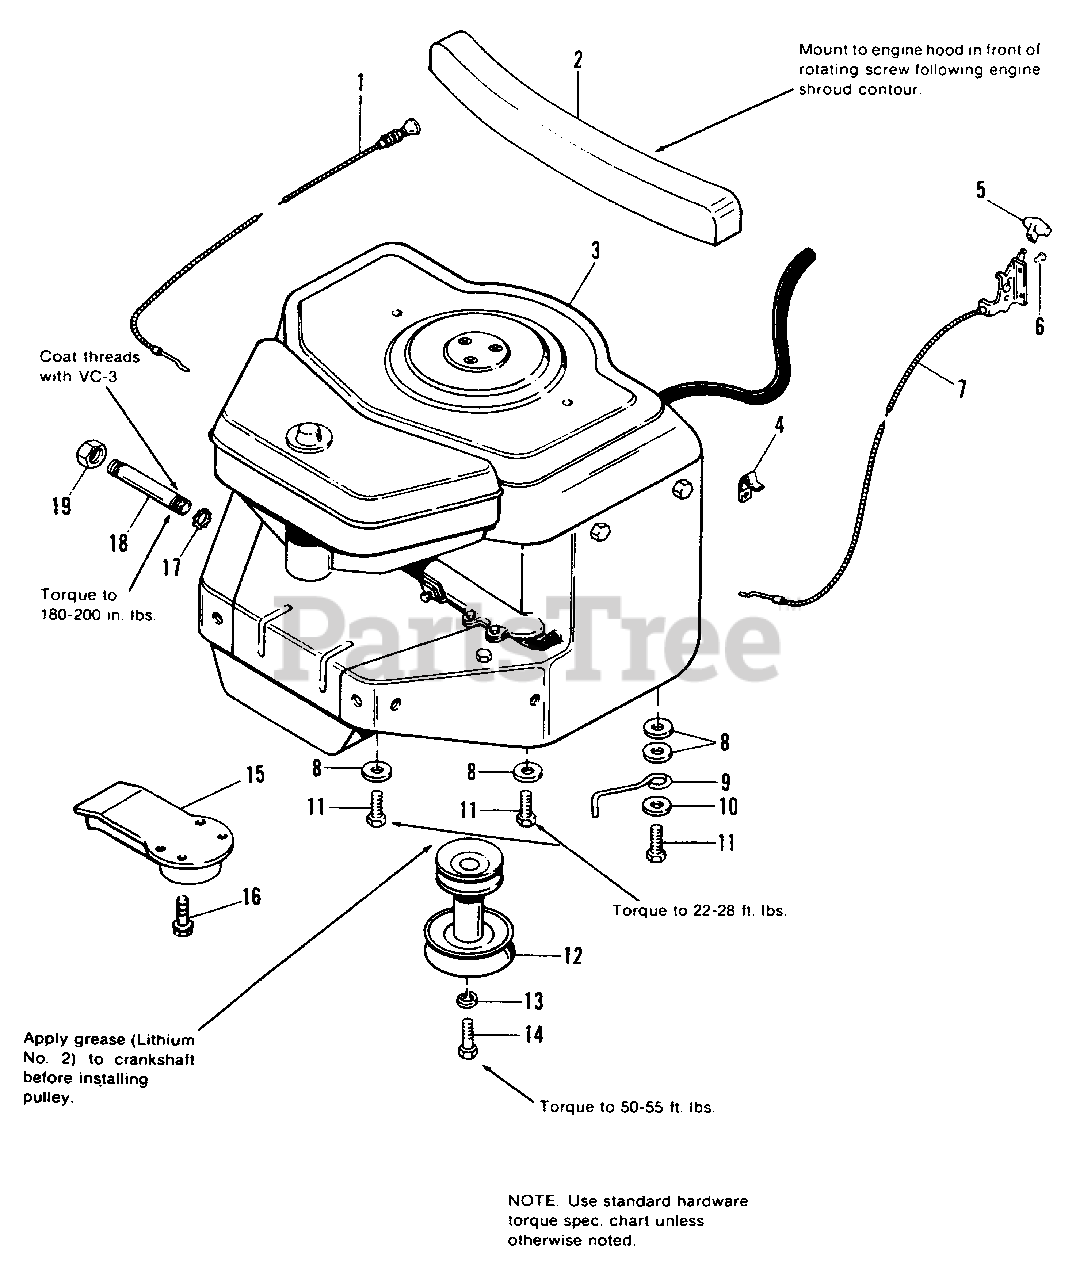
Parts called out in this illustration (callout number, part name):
1	CHOKE (Used on 6118)
1	CHOKE (Used on 6116)
2	BAFFLE, Engine, Rear
4	CLIP, Wire
5	KNOB
6	RIVET, Pop, 1/4 x 7/16
7	CONTROL ASSY.
8	WASHER, Plain (Used on 6116)
9	STOP, Belt, (Used on 6116)
10	WASHER, Plain, 3/8 (Used on 6116)
11	SCREW, Taptite, 3/8-16 x 1-3/4 (Used on 6116)
12	PULLEY ASSY., Engine
13	LOCKWASHER, 7/16
14	CAPSCREW, Hex, 7/16-20 x 1-1/4
15	EXTENSION ASSY., Muffler
16	SCREW, Hex Thd., Cutting, #8-32 x 3/8
17	LOCKNUT, Conduit, 3/8 (BC-38)
18	PIPE, Oil Drain
19	PIPE, Cap, Hex
